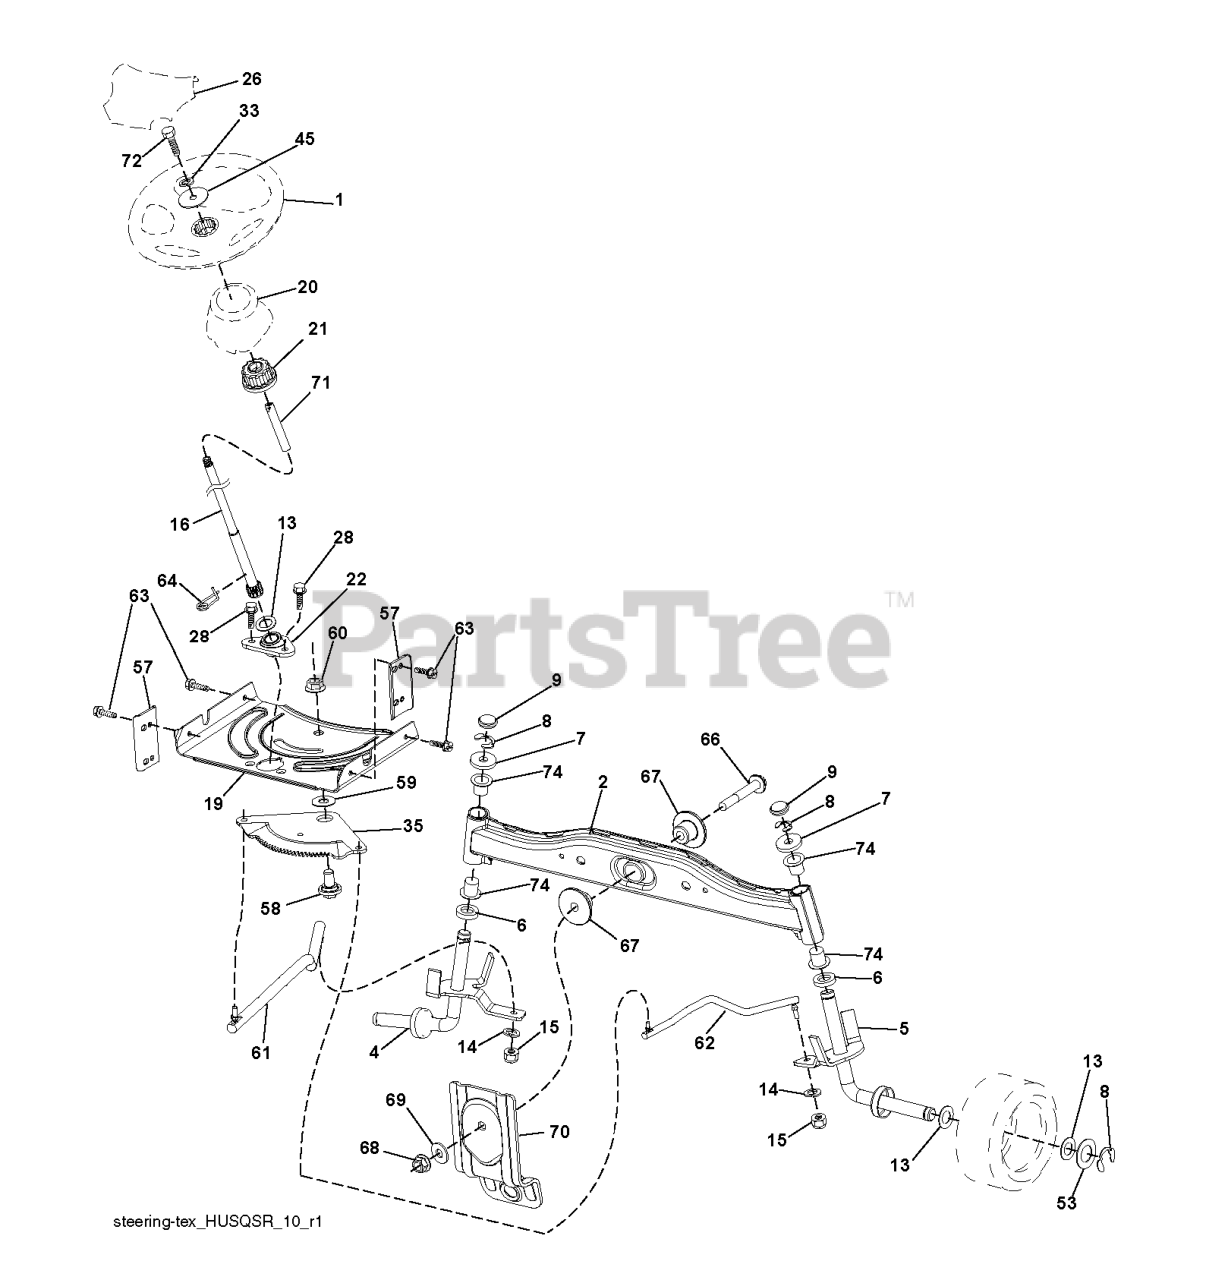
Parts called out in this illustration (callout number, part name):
1	RP WHEEL.STEER.HUSQ.PREM.OVMLD
2	AXLE HALF ASM-WELDED
4	SPINDLE.WELDED.LH.15"TEX
5	SPINDLE.WELDED.RH.15"T
6	THRUST WASHER
9	CAP.SPINDLE.BLACK
14	WASHER, LOCK 3/8
15	NUT CROWNLOCK 3/8-24
16	SHAFT.STEER.3/4.PLATED.TEX
19	PLATE.STEER.DDL.NLT/NG
20	BOOT, STEERING
21	ADAPTER, WHEEL STNG..
22	STEERING.SUPT.LOWER.
26	RP INSERT.CAP.WHL.STRG.HUSQ.
28	SCREW, 3/8-16X3/4
33	WASHER.LOCK.HVY.HLCL.SPR.5/16
35	GEAR.SECTOR.PLATE.DDL.
45	WASHER.11/32
53	WASHER.HARDENED
57	BRACKET.UPSTOP.TEX
58	BOLT.SHOULDER.SECTOR.P
59	WASHER.THURST.SECTOR.S
60	NUT FLANGE LOCK 5/8-11
61	DRAGLINK.LH.BALLSTUD.D
62	DRAGLINK.RH.BALLSTUD.D
63	SCREW
64	RETAINER.CLIP.SPRING.S
66	BOLT HEX FGHD 7/16-14 X 3 SERR
67	BUSHING.PM.FRONT AXLE
68	NUT.LOCK.FLANGE.7/16
69	WASHER.1.5X.505X.118
70	BRKT.DECK.SUSPENSION.F
71	SHAFT.EXTEN.STRG.SPLINE
72	BOLT 5/16-18 X 4 W/PATCH
74	BRNG T
